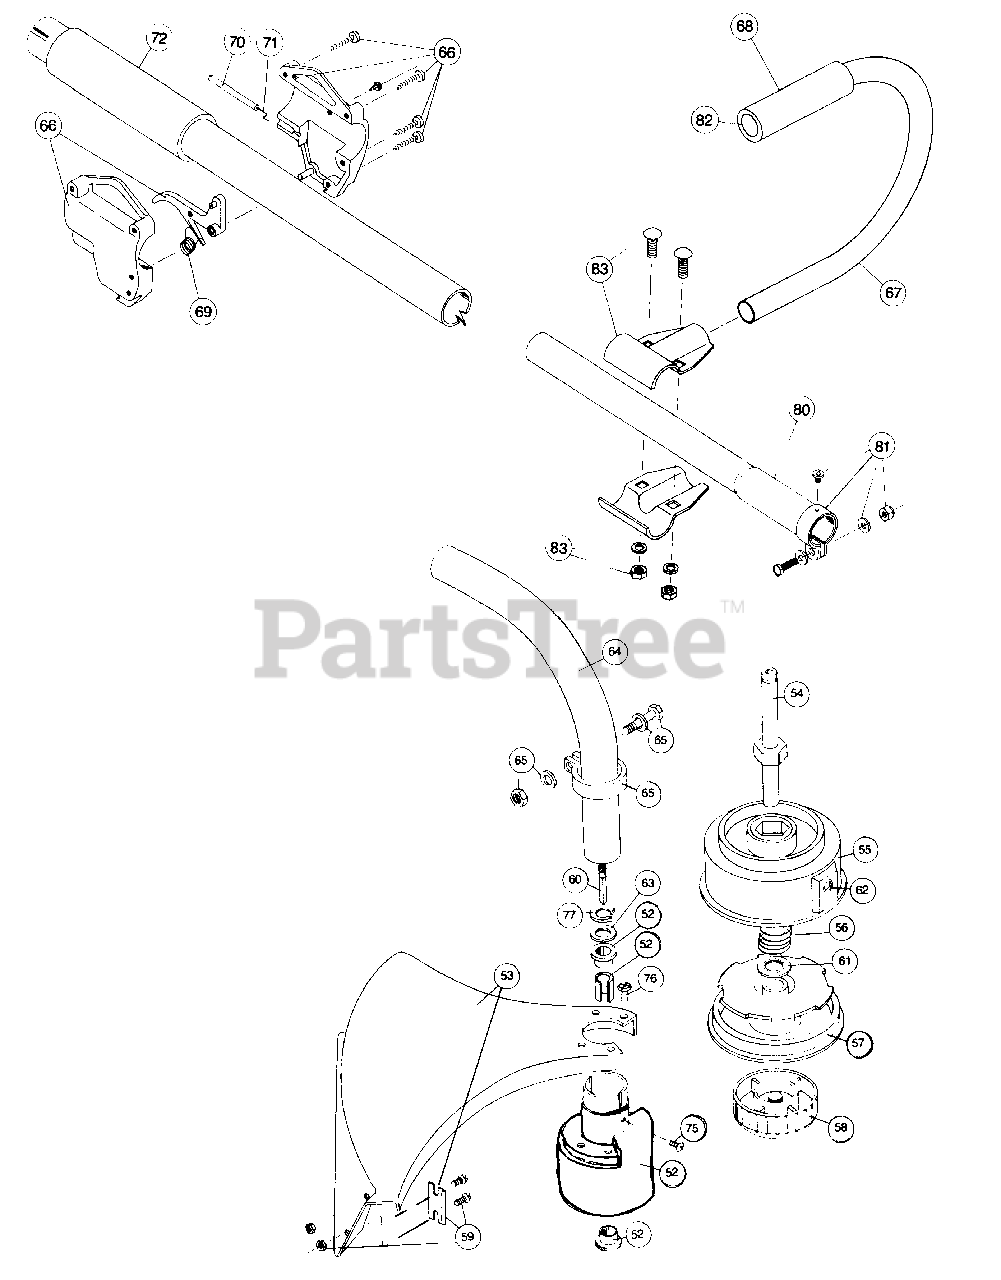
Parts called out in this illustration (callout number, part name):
52	Bushing housing assembly
53	Guard and blade assembly
54	Spool shaft
55	Outer spool and eyelet assembly
57	Inner reel
58	Bump head knob assembly
59	Blade assembly
60	Flexible drive shaft
61	Retainer (10 pack)
64	Lower drive shaft housing assembly
65	Lower clamp assembly
66	Throttle trigger assembly
67	J-handle assembly (Includes 68 & 82)
69	Throttle trigger spring
70	Throttle cable housing assembly
71	Throttle cable
72	Main handle grip
75	Anti-rotation screw
76	Guard mounting screw assembly
77	Retaining ring
80	Upper drive shaft housing assembly
81	Split boom clamp assembly
82	Tube closure
83	Bracket assembly
